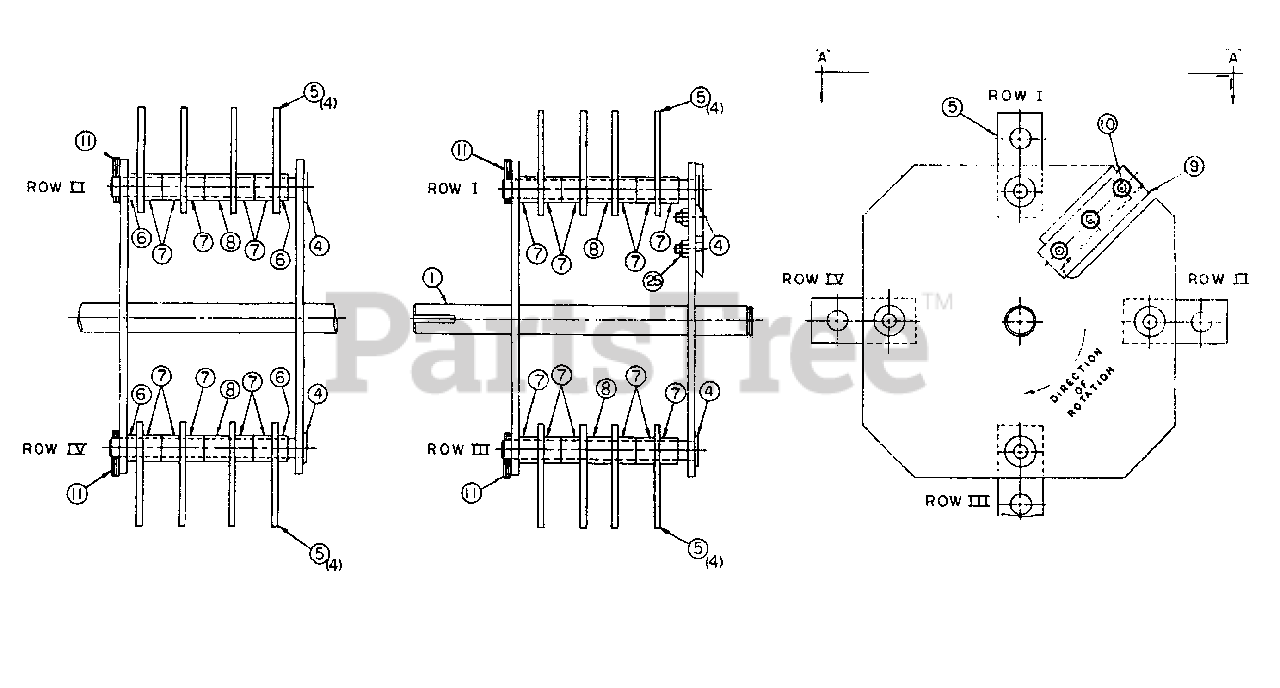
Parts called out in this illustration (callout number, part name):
1	ROTOR WELDMENT
4	HAMMER ROD
5	HAMMER
6	SPACER 5/16 LG.
7	SPACER 5/8 LG.
8	SPACER 7/8 LG.
9	CHIPPER KNIFE
10	5/16-18 x 1" LG FLAT HD HEX SOCKET CAP SCREW
11	GROOVE PIN
25	5/16-18 UNC GRIPCO LOCK NUT
